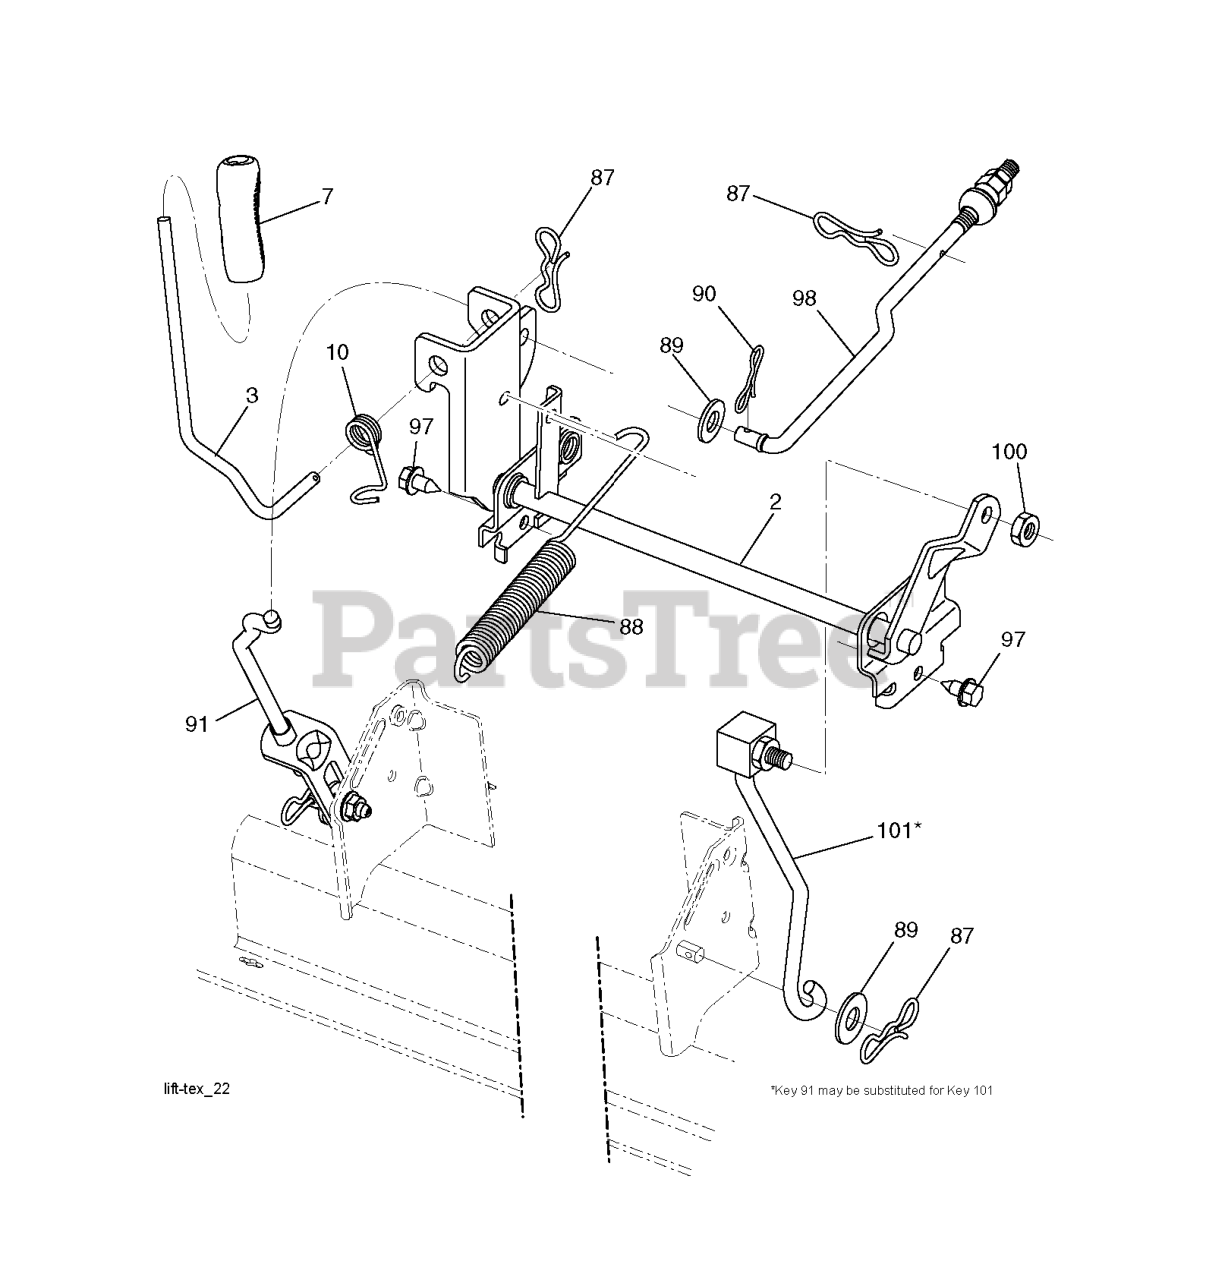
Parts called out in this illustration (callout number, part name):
2	SHAFT.ASM.CROSS.LIFT
3	LEVER.LIFT.HANDLE.LT
7	GRIP.HANDLE.LIFT.PVC.BLACK
10	SPRING.TORSION.LIFT.HANDLE
87	PIN.COTTER.7/16.BOW TI.
88	SPRING.LIFT.ASSIST
89	WASHER.CLEAR.ZINC
90	PIN.COTTER.5/16.BOW TI
91	LINK.ASM.LIFT.REAR
97	SCREW, 3/8-16X3/4
98	LINK.ASM.SUSP.FRONT.MW
100	LOCKNUT
101	LINK.ASM.LIFT.FIXE.38/42/46"
